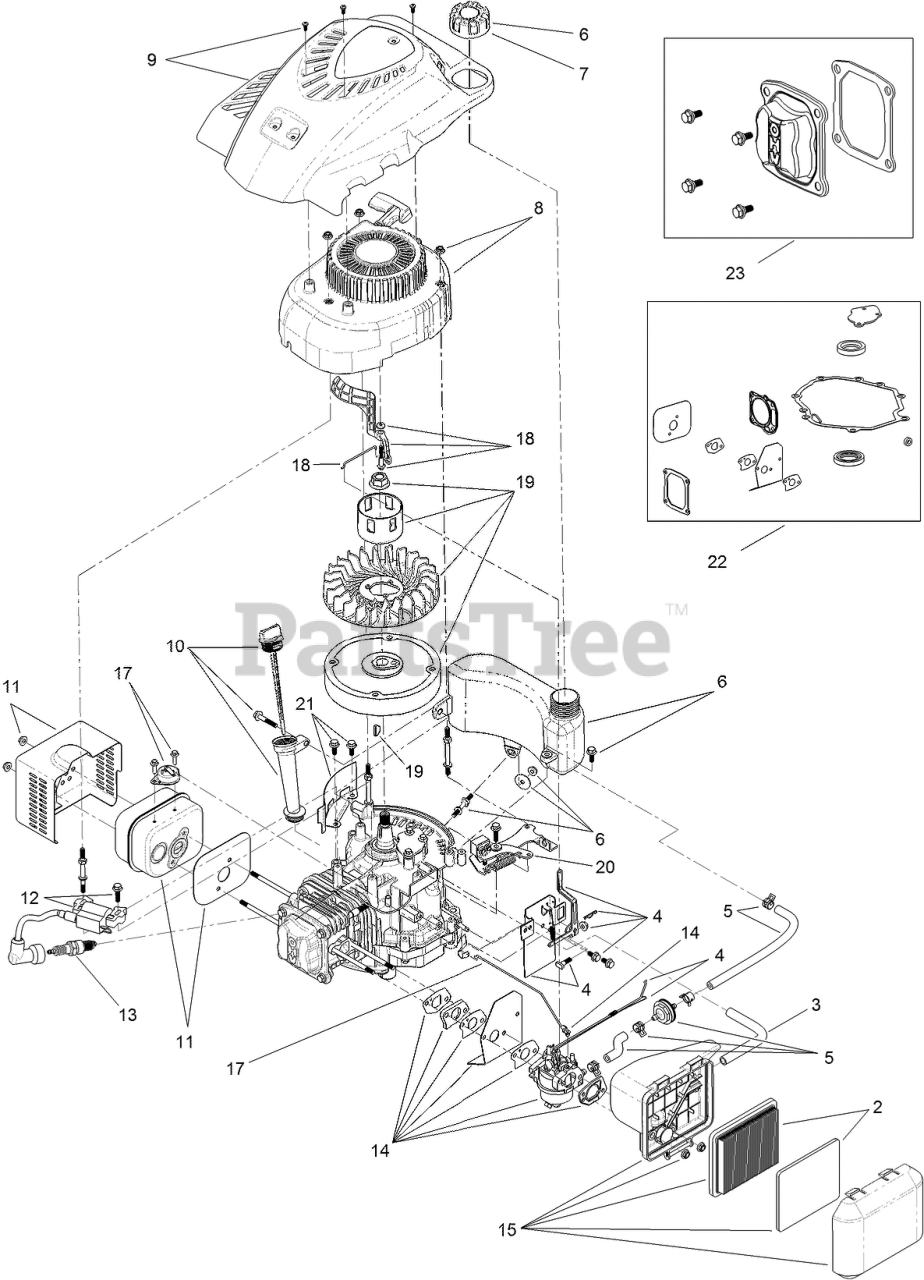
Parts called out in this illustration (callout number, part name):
2	AIR FILTER AND PREFILTER KIT
3	TUBE-BREATHER
4	GOVERNOR ARM KIT
5	FUEL LINE KIT
6	FUEL TANK KIT (CAP AND HARDWARE)
7	CAP-FUEL
8	SHROUD AND RECOIL ASM
9	Shroud ASM
10	DIPSTICK AND FILL TUBE KIT
11	MUFFLER AND SHIELD KIT
12	IGNITION AND HARDWARE KIT
13	PLUG-SPARK
14	CARBURETOR COMPLETE KIT
14	CARBURETOR REPAIR KIT
15	AIR CLEANER ASM
17	THERMAL CHOKE CONTROL KIT
18	AIR VANE CHOKE KIT
19	FLYWHEEL AND FAN KIT
20	BRAKE ASM RECOIL KIT
21	FLYWHEEL SHIELD KIT
22	SEAL AND GASKET KIT
23	VALVE COVER KIT
